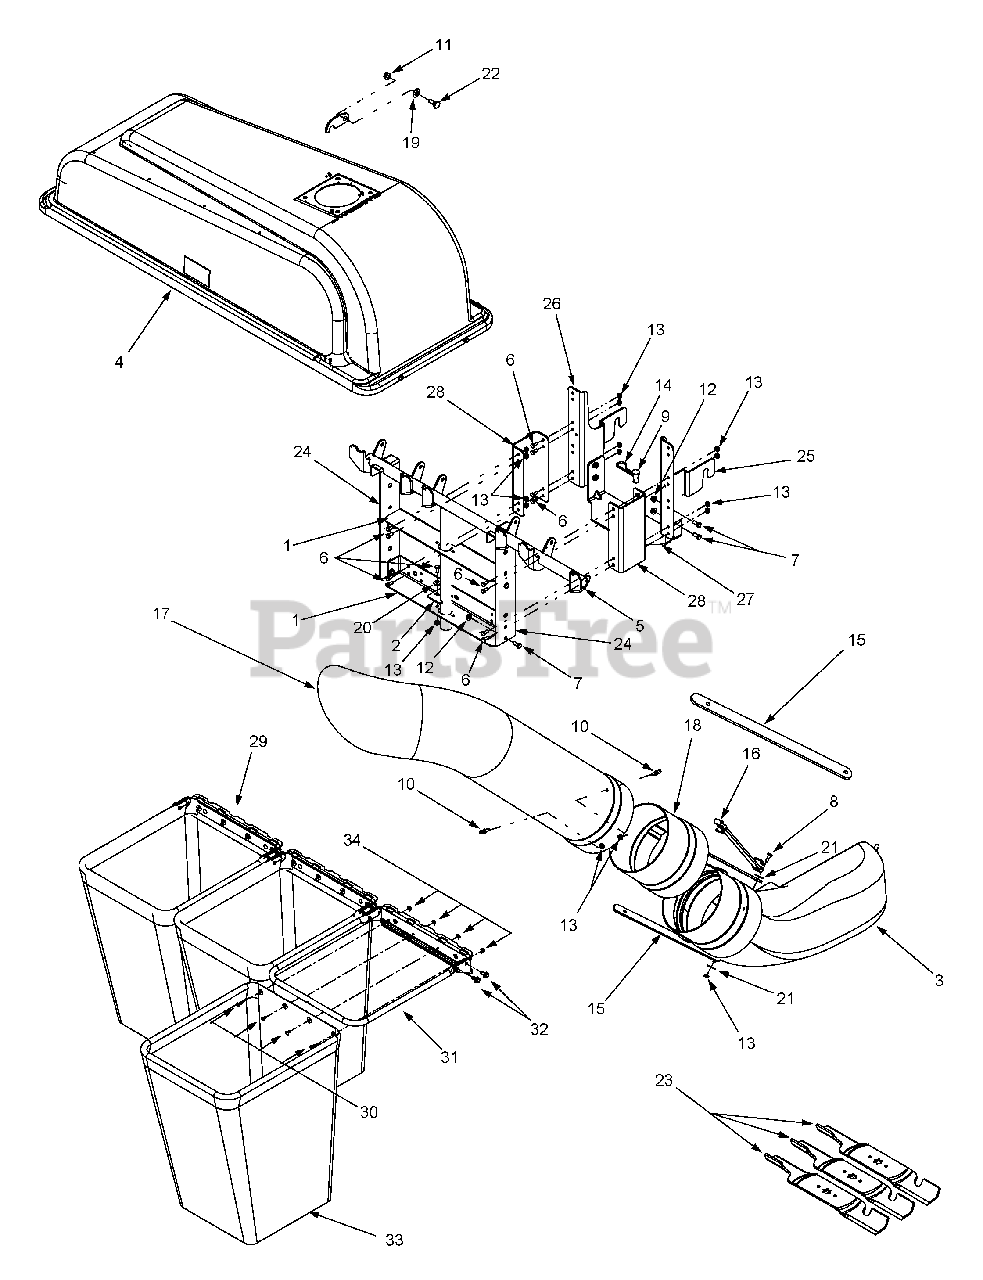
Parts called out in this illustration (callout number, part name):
3	Elbow Chute Assembly
4	Grass Catcher Cover Assembly
7	Hex Cap Screw, 5/16-18 x .75
8	Hex Cap Screw, 1/4-20 x .75
9	Clevis Pin
10	Grass Catcher Pin, 1/4-20
11	Hex Flange Lock Nut, 3/8-16
12	Hex Flange Lock Nut, 5/16-18
13	Hex Flange Lock Nut, 1/4-20
14	Internal Cotter Pin, .148 x 3
15	Chute Strap, 11.65
16	Retainer Strap Assembly
17	Chute Tube
18	Extension Tube
19	Belleville Washer
20	Bell Washer, .265 x .75 x .062
21	Flat Washer .265 x 1.0 x .030
22	Shoulder Screw, .50 x .27, 3/8-16
23	High Lift Blades 18.50"
30	Screw, #10-24 x .5
33	Grassbag
34	Hex Sems Nut, #10-24
